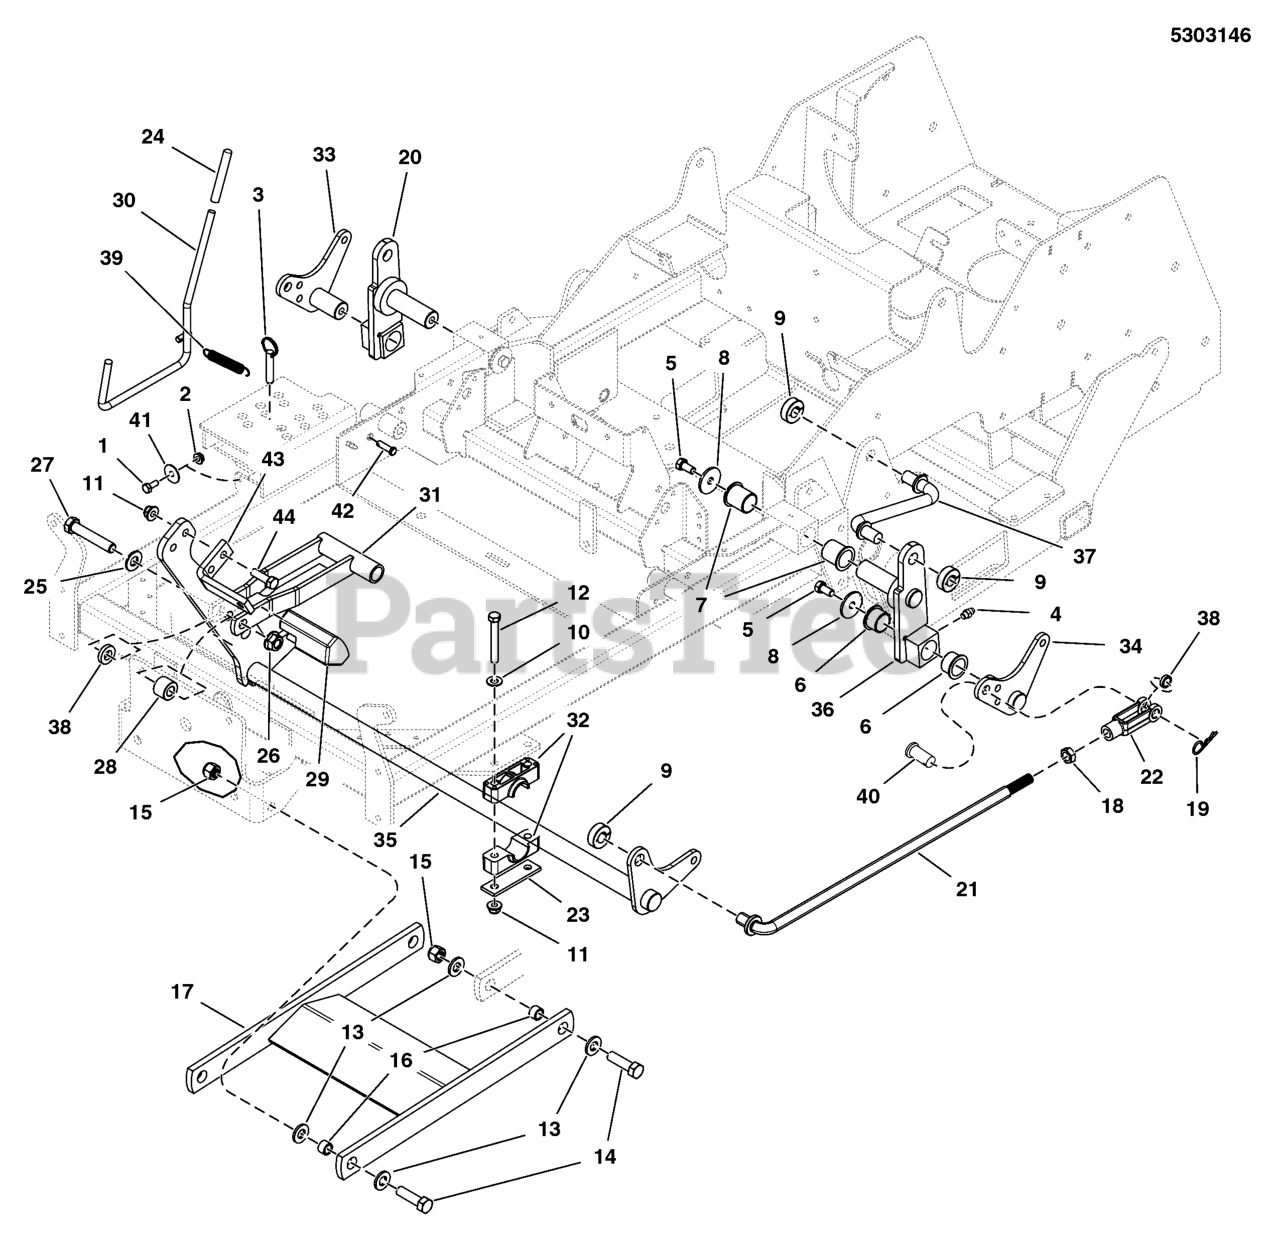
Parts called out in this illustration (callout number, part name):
1	HHCS, 1/4-20 X 0.625, GR5, ZINC/CLEAR
2	NUT, 1/4-20 HEX SERR. FLANGE
3	PIN, HITCH, 1/2 X 2.00 OAL, YP
4	GREASE FITTING, 1/4-28 STRAIGHT
5	BOLT, 3/8-16 X 3/4, PLT W/PATCH
6	BUSHING, 1.00X1.13X.75, PLA
7	BUSHING, 1.00 X 1.13 X 1.38, PLASTIC
8	WASHER, .390 X 1.50 X .109, YZ
9	COLLAR, 5/8 SPLIT
10	WASHER, 3/8 SAE
11	NUT, 3/8-16 HEX NYLOCK FLANGE
12	BOLT, 3/8-16 X 2-3/4" GD5 CZ
13	WASHER, 1/2 GD9 YZ
14	BOLT, 1/2-20 X 1-3/4" GD8 CZ
15	NUT, Hex, Nylon Lock, 1/2-20
16	INSERT, BEARING
17	WELD, PULLER BAR, IS600 - BLK
18	NUT, 1/2-20 HEX JAM
19	PIN, HAIR, .0915 X 1-7/8
20	WELD, REAR LIFT - RH - IS500Z - BLK
21	ROD, DECK LIFT, SNP
22	CLEVIS, 1/2-20, STEEL, CLEAR ZINC
23	PLATE, PIVOT BLOCK SUPPORT - BLK
24	GRIP, FOAM, .475 X 4.35 X .095
25	WASHER, 1/2 SAE
26	NUT, Hex Flange, Nylock, 1/2-13
27	BOLT, 1/2-13 X 2-3/4 GD5 CZ
28	SPACER, .52 X 1.00 X .75, CZ
29	PEDAL, Rubber
30	WELD, Rod, Deck Lift - BLK
32	PIVOT BLOCK, PLASTIC
33	WELD, HANGER, REAR, RH - BLK
34	WELD, HANGER, REAR, LH - BLK
35	WELD, DECK LIFT SHAFT, IS600
36	WELD, REAR LIFT - LH - IS500Z - BLK
37	ROD, SUSPENSION LINK, IS600
38	SPACER, .52 X 1.00 X .22, PM, CZ
39	SPRING-EXT, .740 ODX2.025LGX.072WR, BLK
40	CLEVIS PIN, 1/2 X 1.36 SAE STANDARD
41	WASHER, 1/4 FENDER
42	CLEVIS PIN, 1/4 X 1/2, CZ
43	PEDAL, FOOT - BLK
44	BOLT, 3/8-16 X 1-1/4" GD5 CZ
